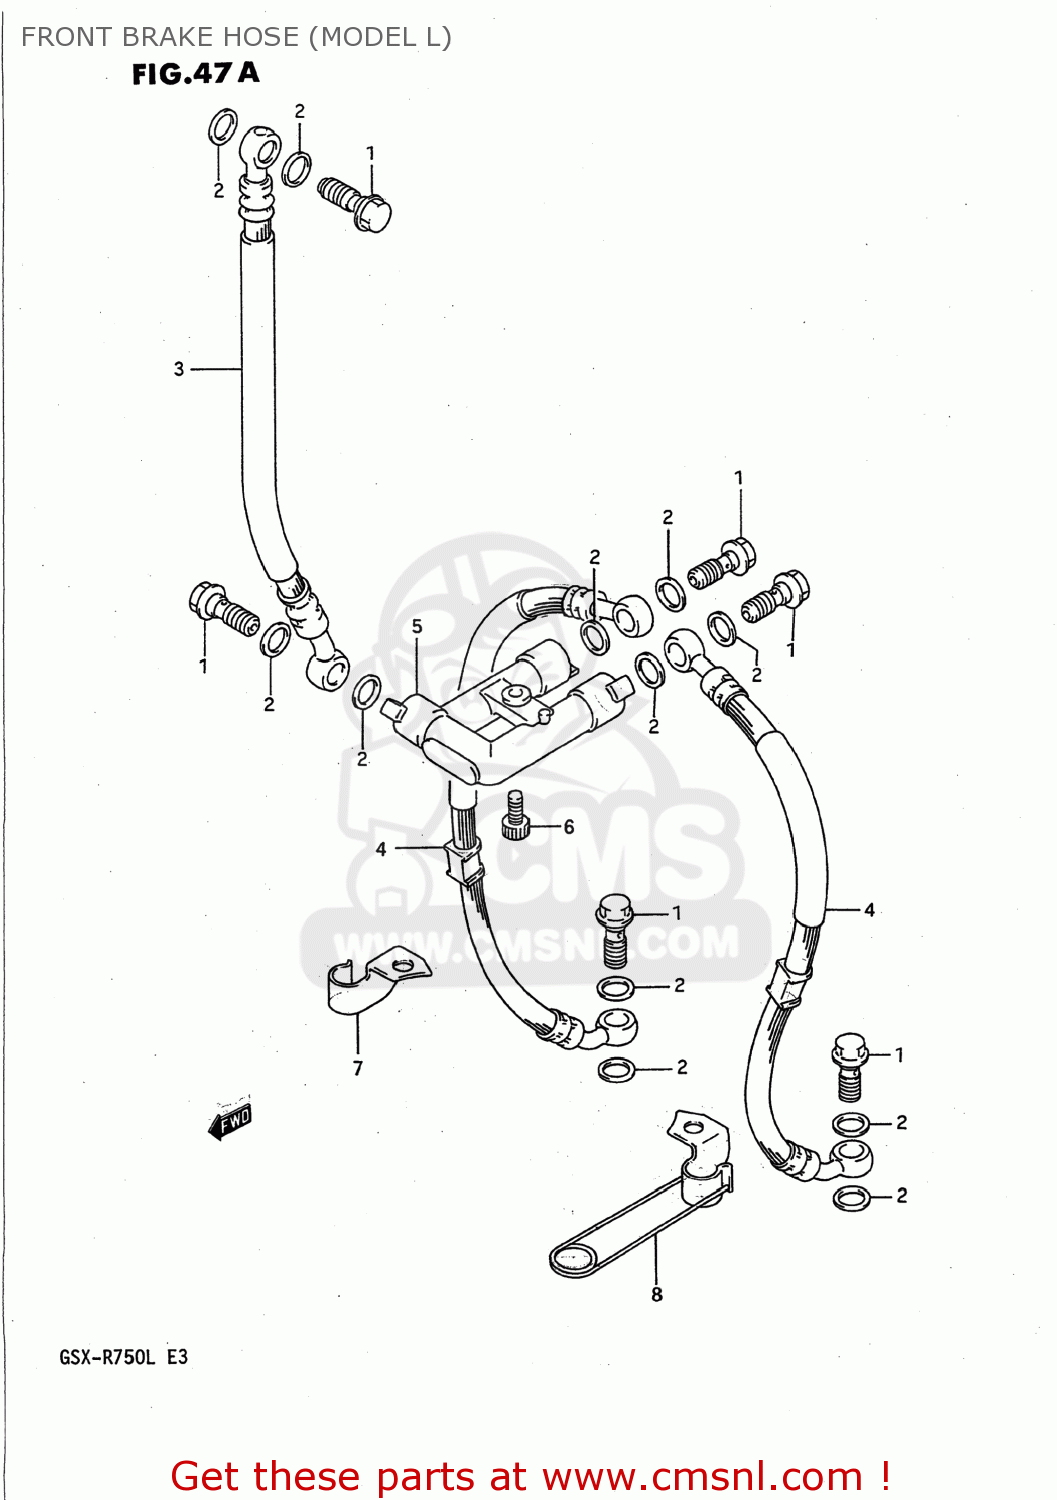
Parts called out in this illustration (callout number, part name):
1	BOLT UNION
2	WASHER(10X15X1.5)
3	HOSE COMP,FRONT BRAKE
4	HOSE,FRONT BRAKE
5	JOINT,BRAKE HOSE
6	BOLT
7	CLAMP,FRONT BRAKE HOSE
8	CLAMP,FRONT BRAKE HOSE
